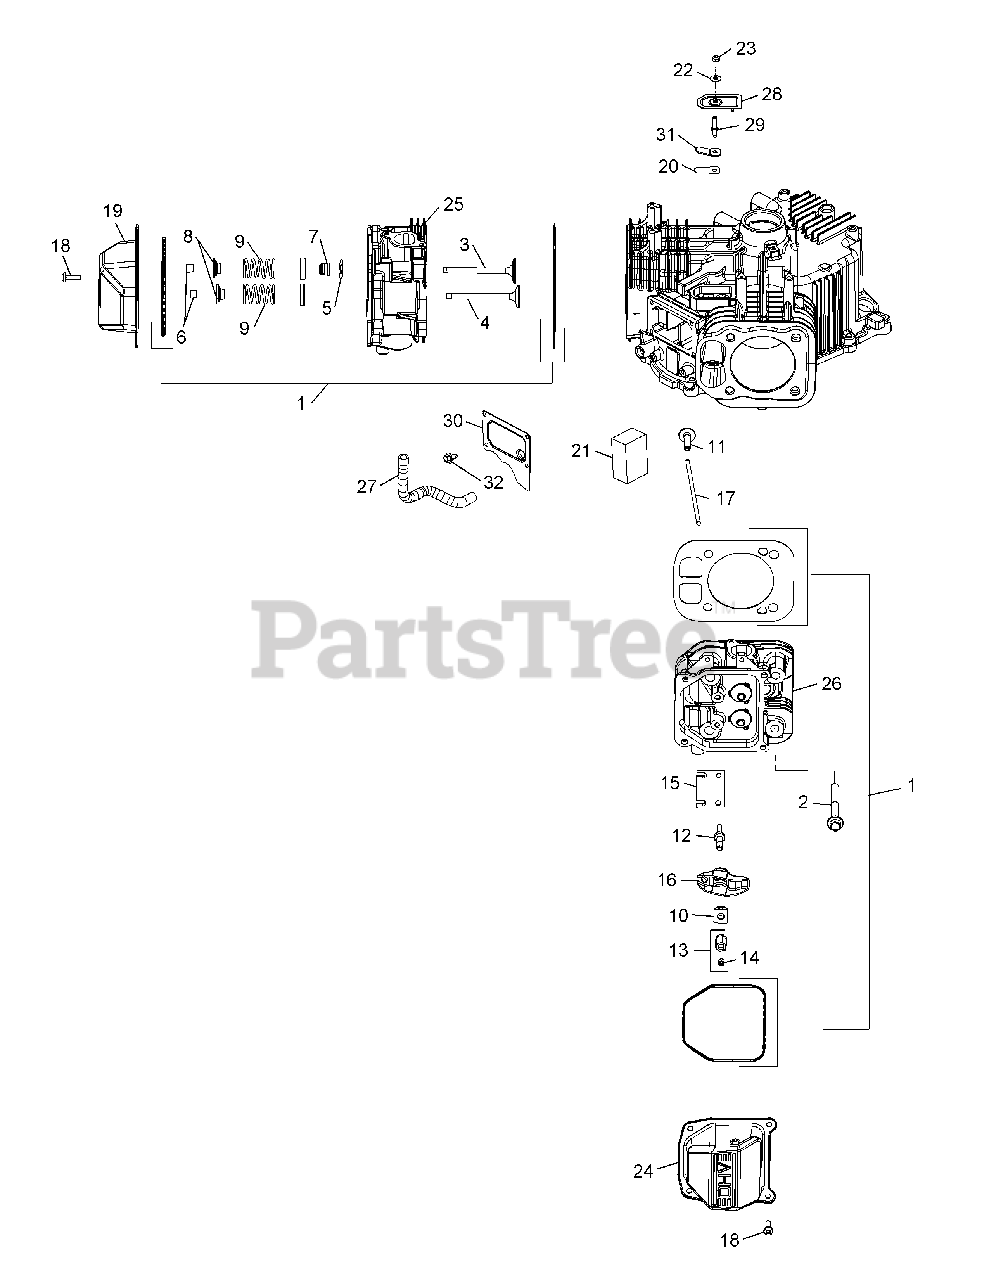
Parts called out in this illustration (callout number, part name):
1	Cylinder Head Gasket Kit
2	Flange Screw, M10 x 1.5 x 90
4	Exhaust Valve
5	Spacer (.010")
6	Retainer Kit
7	Valve Band Seal
8	Valve Spring Cap
9	Valve Spring
10	Rocker Arm Pivot
13	Hex Nut Assembly (Inc. #14)
18	Pan Head Screw
20	Breather Reed
21	Breather Filter
22	Sealing Washer
23	Lock Nut, M5 x 8
24	Rocker Cover
25	Cylinder Head Assembly Kit, #1
26	Cylinder Head Assembly Kit, #2
27	Breather Hose
28	Breather Cover
30	Breather Media Cover
31	Reed Retainer
32	Thread Forming Screw
